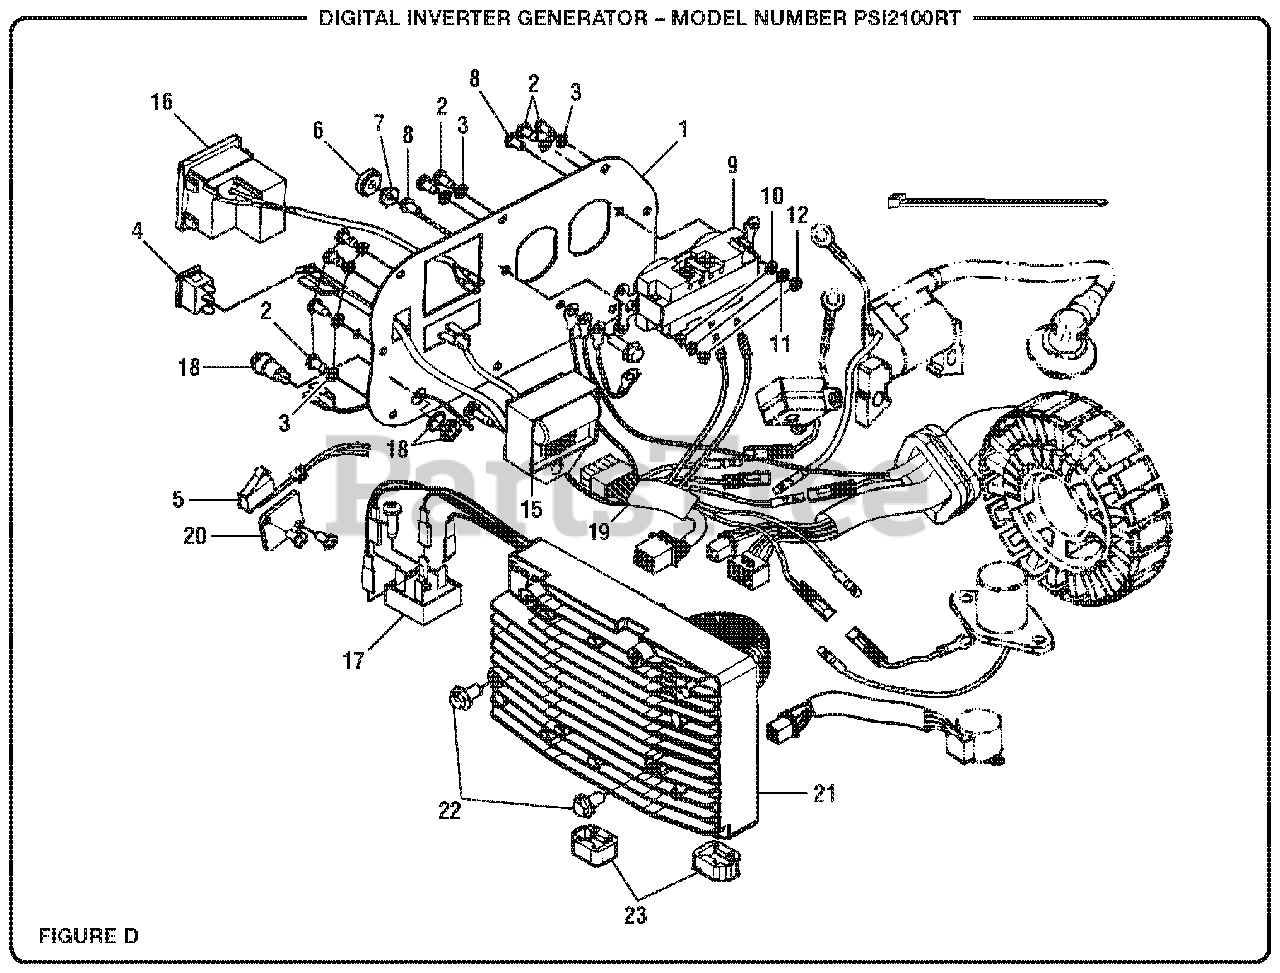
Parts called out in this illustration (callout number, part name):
1	Control Panel Faceplate
2	Screw (ST4.2 x 13 mm)
3	Washer (IDdia4 x OD10 x 1.6t)
4	Smart Throttle Switch
5	On/Off Switch
6	Knurled Nut (M5)
7	Flange Nut (M5)
8	Screw (M4 x 12 mm)
9	120V-20A Duplex Receptacle
10	Washer (ID4 x OD8 x 0.5t)
11	Spring Washer (M4)
13	Bolt (M6 x 16 mm, Flange Hd.)
14	Ground Line Assembly
15	Indicator Light TCI Set
16	12V DC Receptacle
17	12V AC to DC Regulator
19	Multiple End Control Panel
20	Main Switch Cover
21	Inverter Module
22	Bolt (M6 x 12 mm)
